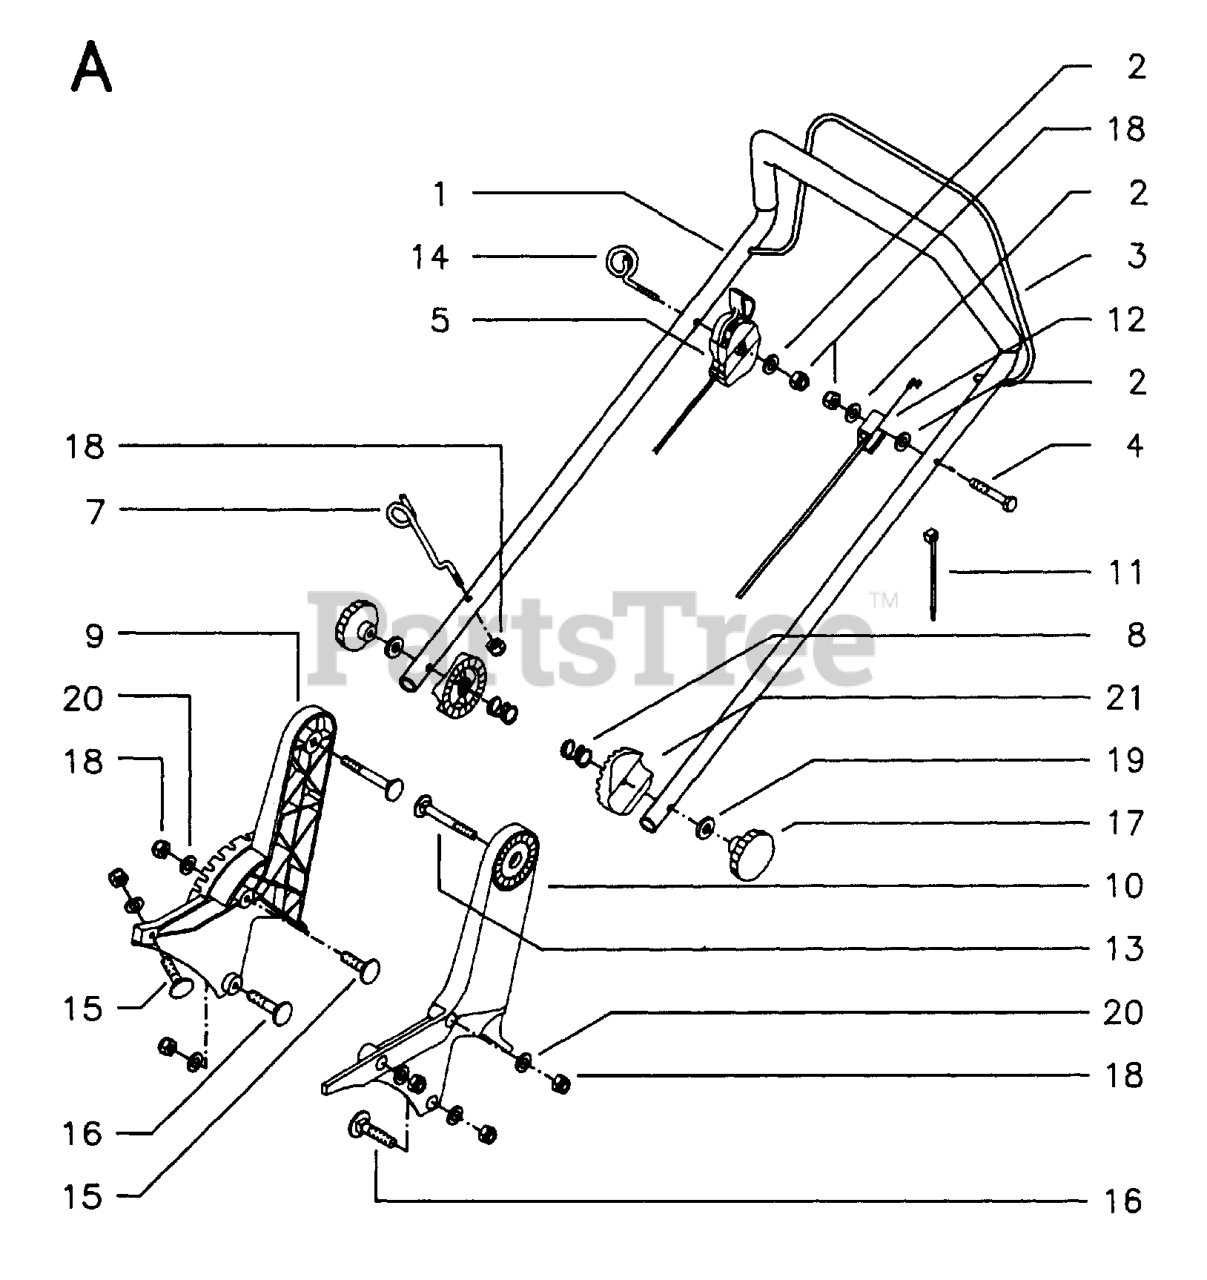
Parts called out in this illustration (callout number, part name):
5	THROTTLE TRIGGER
12	WIRE R 47/47S/47SE
15	REPL BY 515 71 16-20
18	LOCKNUT M6
